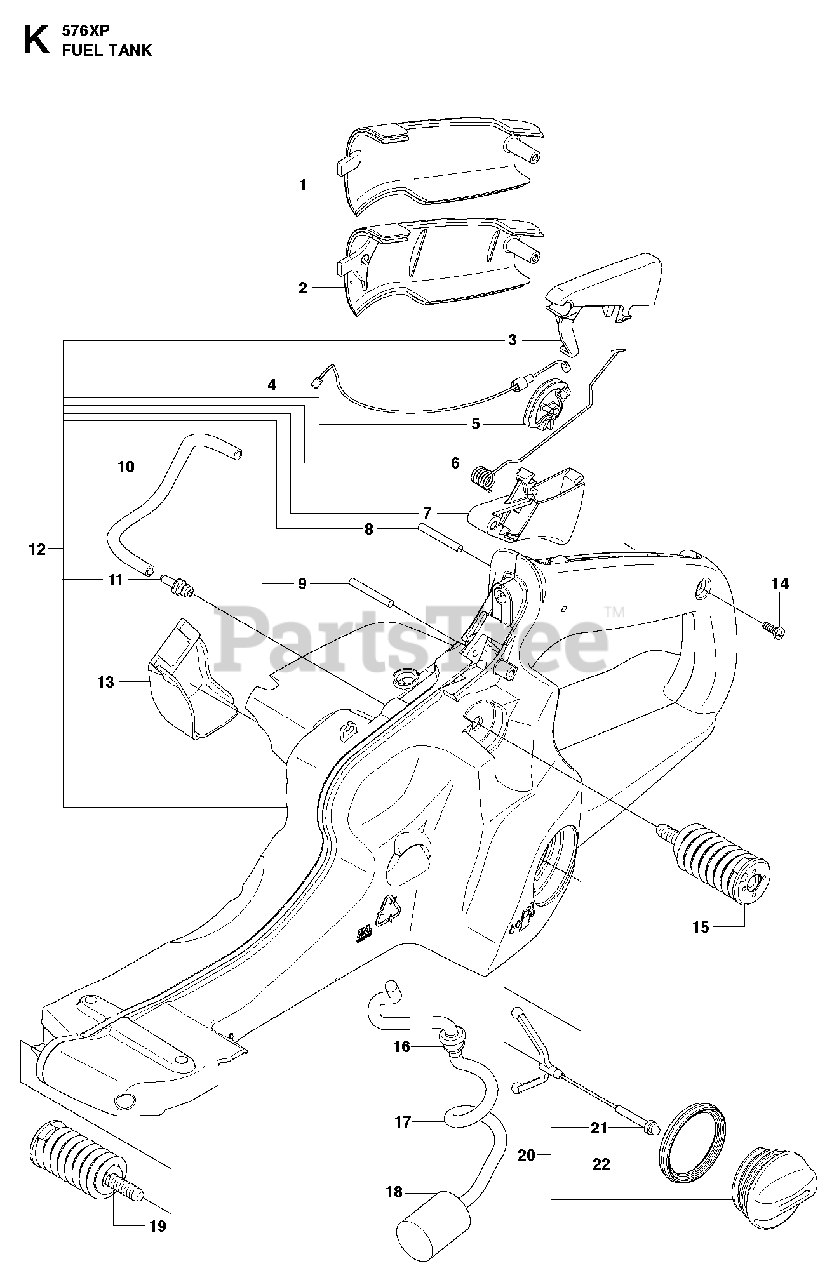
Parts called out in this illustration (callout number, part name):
1	COVER
2	COVER
3	THROTTLE LOCK
4	THROTTLE WIRE
5	LEVER
6	SPRING
7	THROTTLE TRIGGER
8	PIN 3X25
9	PIN 3X25
10	HOSE
11	FUEL TANK VENT
15	VIBRATION ABSORBER
16	FUEL TANK BUSHING
17	FUEL HOSE
18	FUEL FILTER
19	VIBRATION ABSORBER
20	TANK CAP
21	TANK LOCK
22	SEALING
